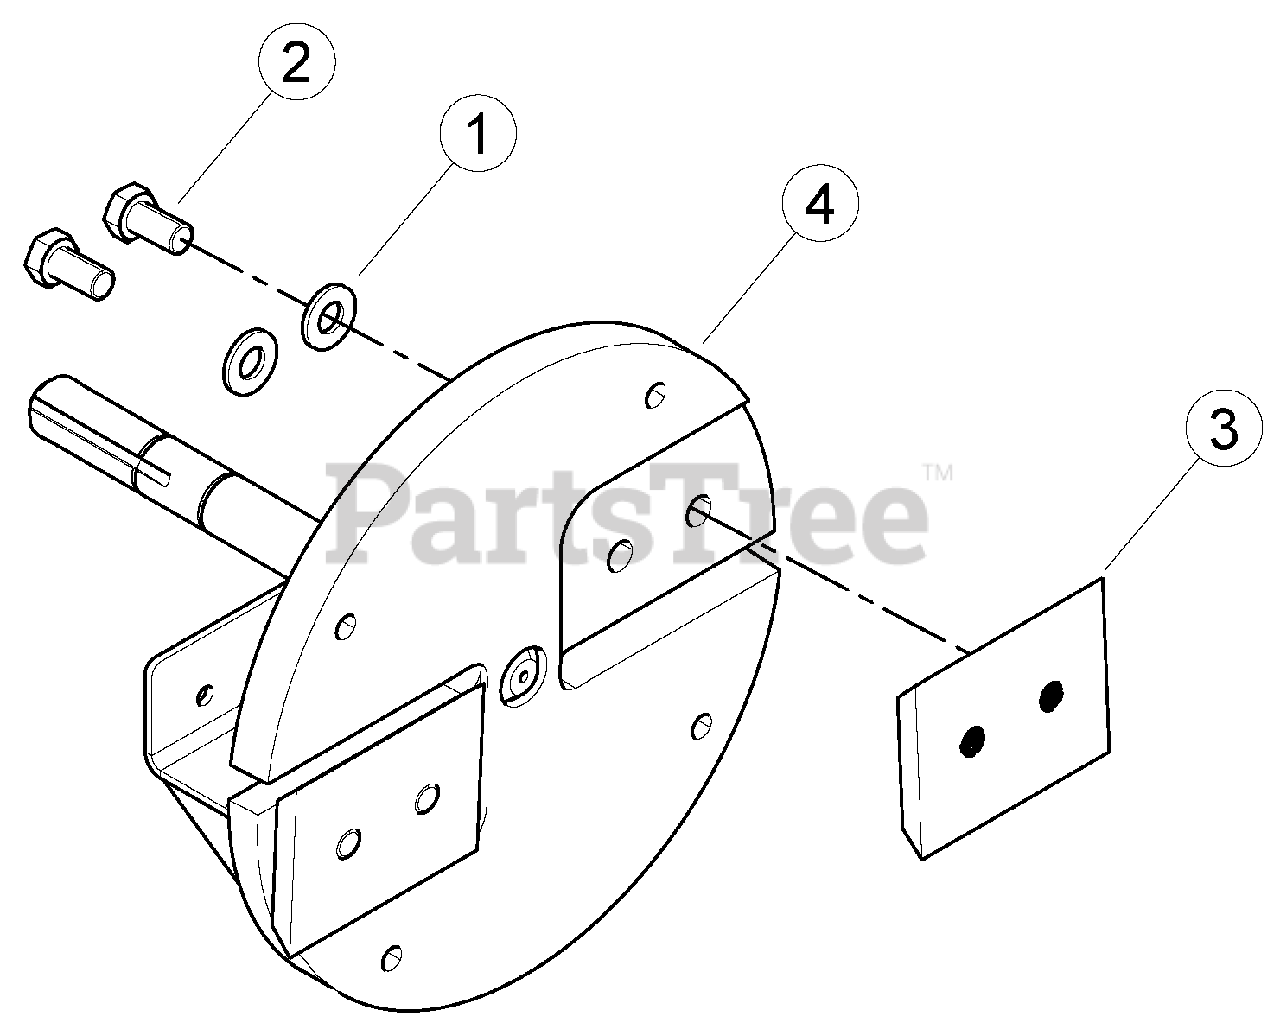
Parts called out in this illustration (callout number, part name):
1	WASHER, 5/8 SAE HARDENED
2	BOLT, M16 X 2.0 X 30 HEX HD W/PATCH
3	KIT, CHIPPER BLADE
4	WELDMENT, 4-1/2 CHIPPER DISK
